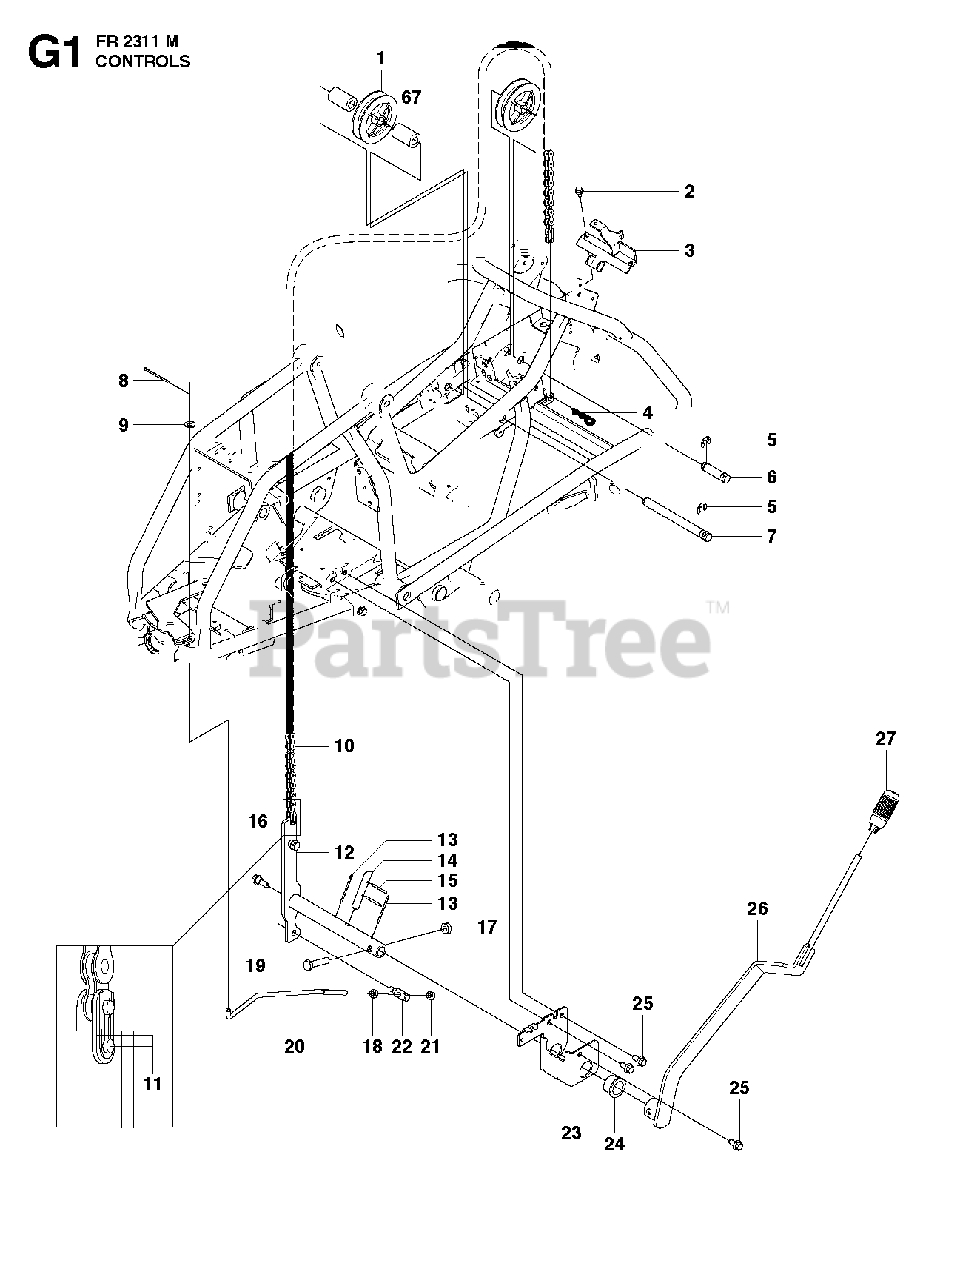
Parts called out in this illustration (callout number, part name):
5	LOCK RING
8	SPLIT PIN
9	WASHER BRB 8.4X17
13	COTTER PIN
14	RP PIN
18	NUT
21	LOCKNUT M8
24	BUSH
